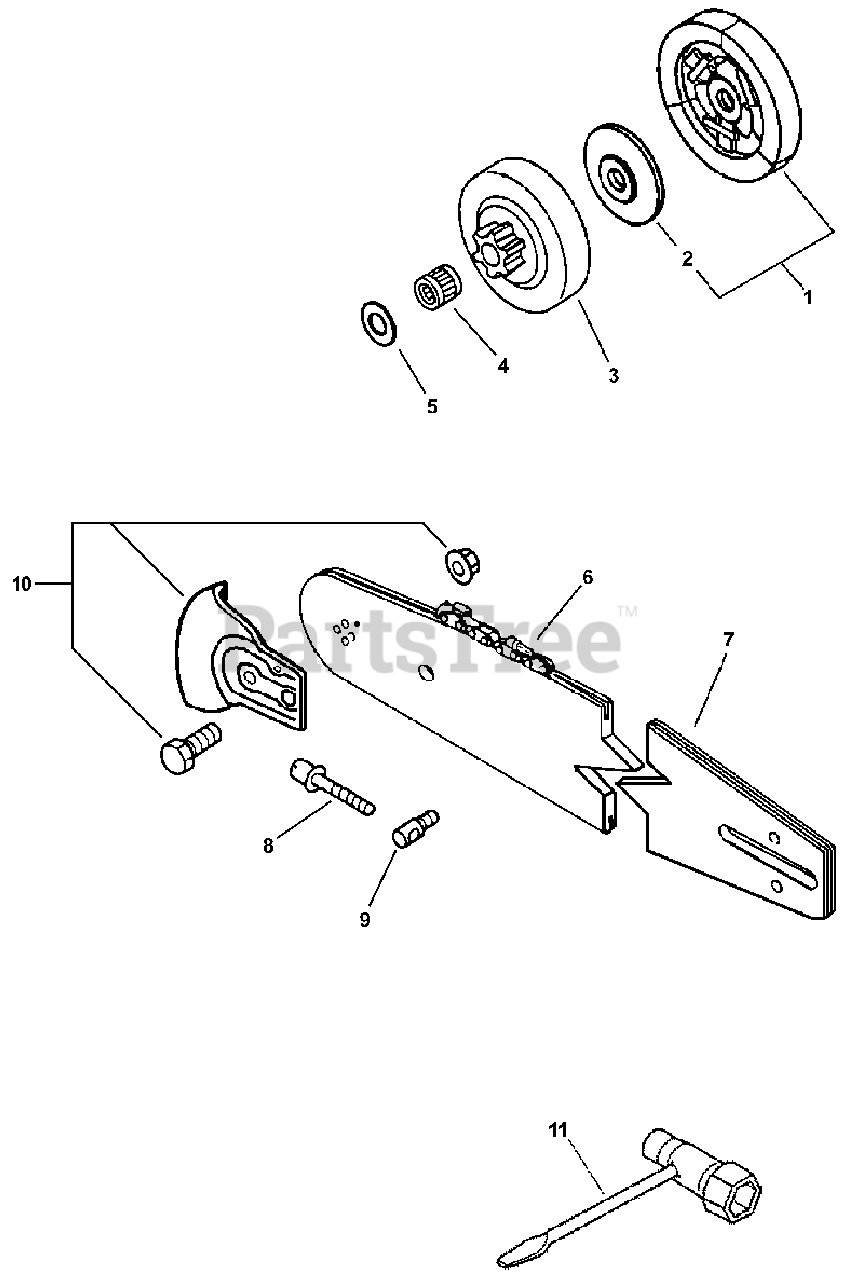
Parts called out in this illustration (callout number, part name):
1	CLUTCH ASSY
2	PLATE, CLUTCH
3	DRUM, CLUTCH 3/8"
4	BEARING, NEEDLE 10×13×10
5	WASHER 10.2×24.5×1.2
6	SAWING CHAIN - 12" -- XTRAGUARD
6	SAW CHAIN 14" XTRAGUARD
6	SAW CHAIN 16"
7	GUIDE BAR, 12" DOUBLE-GUARD
7	GUIDE BAR, 14" DOUBLE-GUARD
7	GUIDE BAR, 16" DOUBLE-GUARD
9	TENSIONER, CHAIN
10	KICK GUARD KIT
